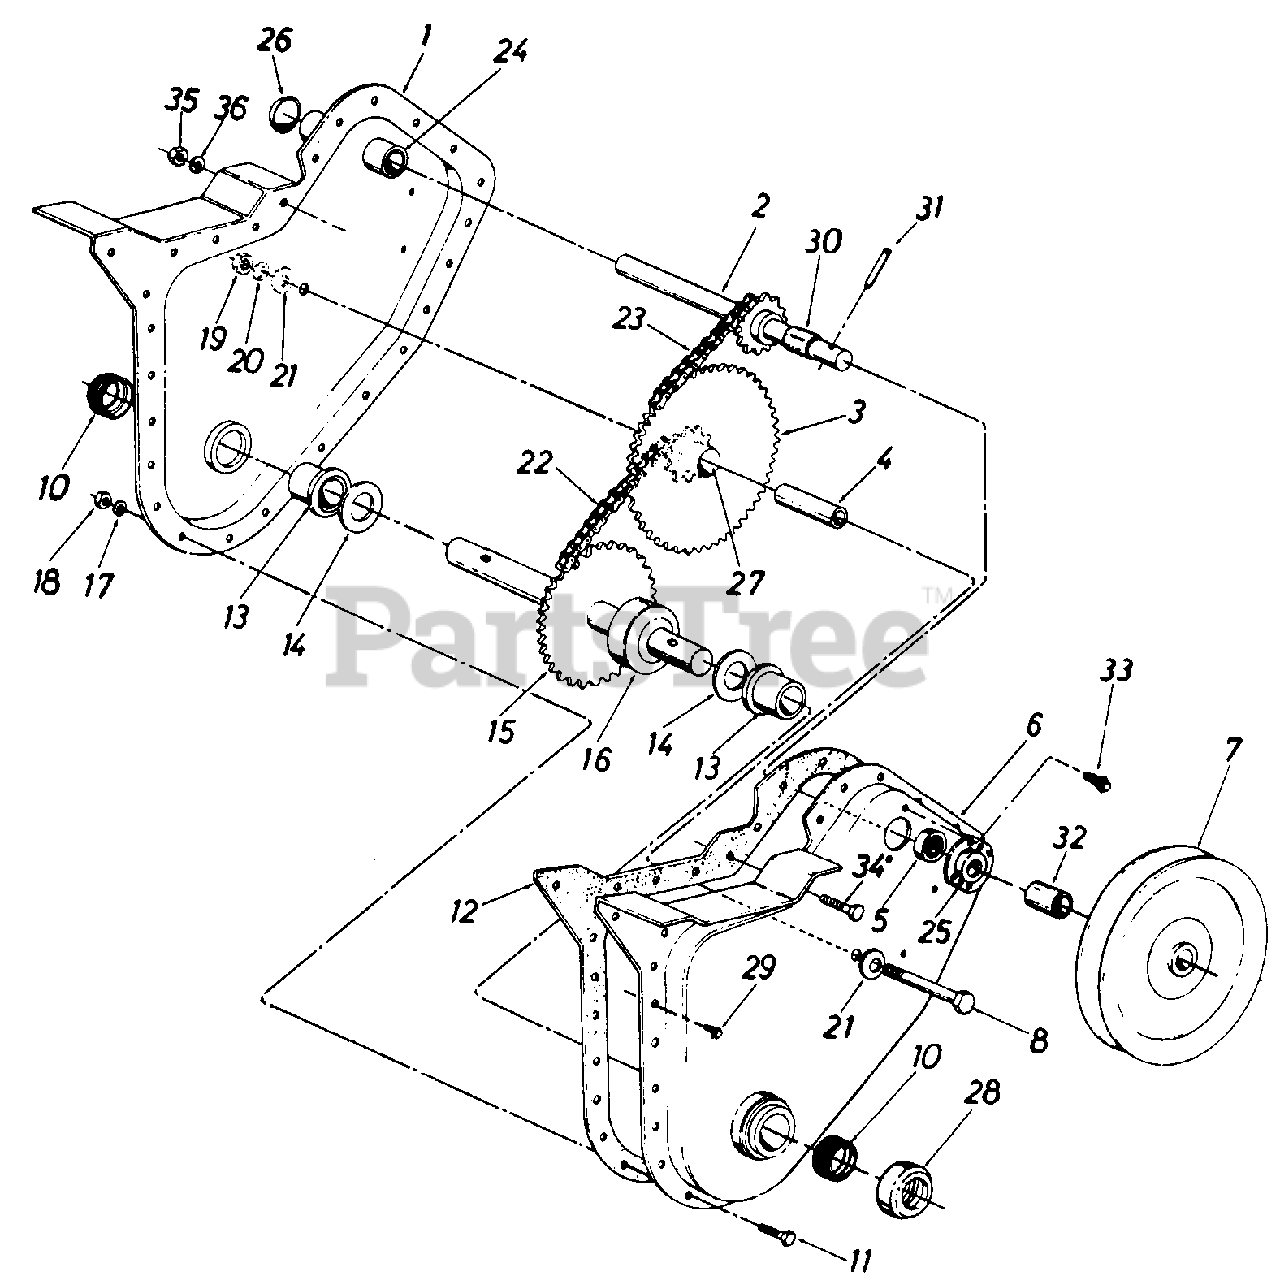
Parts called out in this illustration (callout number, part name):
1	HOUSING-CHAIN-CASE RH
2	SHAFT ASSY-INPUT
3	SPROCKET & HUB ASSY
4	BEARING-INNER RACE
5	BEARING-BALL
6	CHAIN CASE HSG-LH
8	SCREW-HEX 3/8-24 X 2.50
11	SCREW-HEX 1/4-28 X .62
12	GASKET
13	BEARING-FLANGE
14	WASHER-FL-.88 X 1.50 X .030
15	SHAFT ASSY-TINE
17	LOCK WASHER 1/4 DIA
18	NUT-HEX 1/4-28
19	NUT-HEX INS L-3/8-24
20	WASHER-LOCK-3/8
21	WASHER-BELL .3/8ID X 1.12OD X .030
22	#420 CHAIN 1/2 PITCH X 37 LINKS
23	#35 CHAIN 3/8 PITCH X 49 LINKS
25	HOUSING-BRG
26	PLUG-EXPANSION
27	BEARING-SLEEVE
29	SCREW-HEX WASH SF TAPP
31	PIN-SPRING SPIRAL 1/4X1.5 HEAVY DT
33	SCREW-TAP 1/4-20 X .38
34	SCREW-HEX 5/16-18 X .75
35	NUT-HEX 5/16-18
36	WASHER-LOCK-5/16
